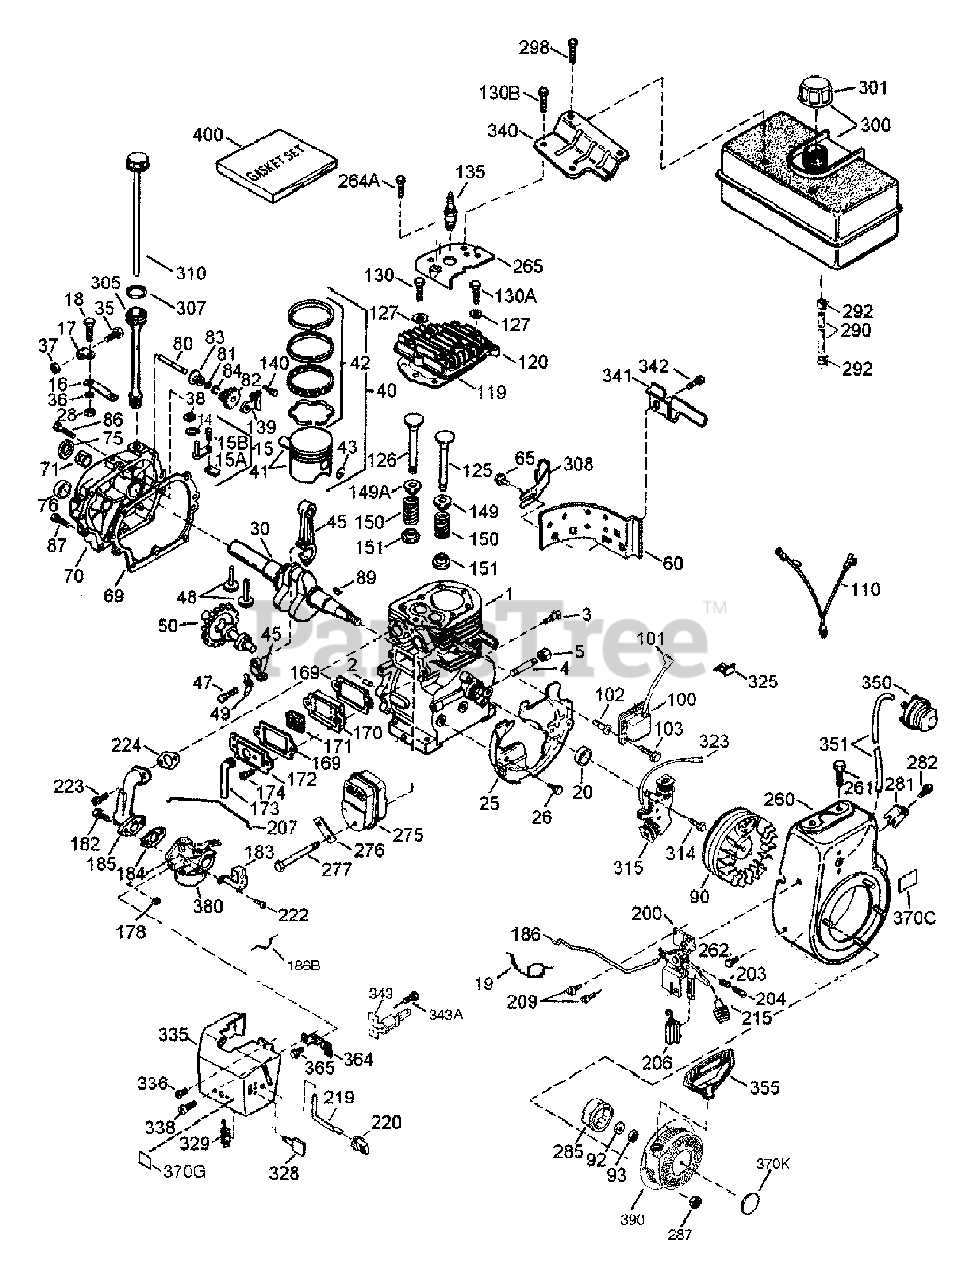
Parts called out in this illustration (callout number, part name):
1	Cylinder Ass'y.
2	Dowel Pin
3	Screw, 1/4-20 x 1/2"
4	Oil Drain Extension
5	Extension Cap
15	Governor Rod
15A	Governor Yoke
15B	Screw, 6-40 x 5/16"
16	Governor Lever
17	Governor Lever Clamp
18	Screw, T-15, 8-32 x 7/16"
19	Speed Control Spring
25	Blower Housing Baffle
26	Screw, 1/4-20 x 19/32"
28	Lock Nut, 8-32
30	Crankshaft
35	Screw, 10-32 x 3/4"
36	Lock Washer
37	Lock Nut, 10-32
38	Retaining Ring
40	Piston, Pin & Ring Set (Std.)
40	Piston, Pin & Ring Set (.010" OS)
41	Piston & Pin Ass'y. (Std.)
41	Piston & Pin Ass'y. (.010" OS)
42	Ring Set (Std.)
42	Ring Set (.010" OS)
43	Piston Pin Retaining Ring
45	Connecting Rod Ass'y.
47	Connecting Rod Bolt
48	Valve Lifter
49	Oil Dipper
50	Camshaft (MCR)
60	Blower Housing Extension
65	Screw, 10-24 x 1/2"
69	Cylinder Cover Gasket
70	Cylinder Cover
71	Crankshaft Bushing
76	Camshaft Seal
80	Governor Shaft
82	Governor Gear Ass'y.
83	Governor Spool
84	Retaining Ring
86	Screw, 1/4-20 x 1-3/16"
87	Screw, 1/4-20 x 1-11/16"
89	Flywheel Key
90	Flywheel (W/Ring Gear)
92	Belleville Washer
93	Flywheel Nut
100	Solid State Ignition
101	Spark Plug Cover
102	Solid State Mounting Stud
103	Screw, T-15, 10-24 x 15/16"
110	Ground Wire
119	Cylinder Head Gasket
120	Cylinder Head
125	Exhaust Valve (Std.)
125	Exhaust Valve (1/32" OS)
126	Intake Valve (Std.)
130	Screw, 5/16-18 x 1-1/2"
130A	Screw, 5/16-18 x 1-25/32"
130B	Screw, 5/16-18 x 39/64"
135	Resistor Spark Plug (RJ19LM)
139	Governor Gear Bracket
140	Screw, 10-24 x 1/2"
149	Valve Spring Cap
149A	Valve Spring Cap
150	Valve Spring
151	Valve Spring Keeper
169	Valve Cover Gasket
170	Breather Body
171	Breather Element
172	Valve Cover
173	Breather Tube
174	Screw, 10-24 x 1/2"
178	Nut & Lock Washer, 1/4-28
182	Screw, 1/4-28 x 1"
183	Choke Bracket
184	Carburetor To Intake Pipe Gasket
185	Intake Pipe
186	Governor Link
186B	Choke Spring
200	Control Bracket
203	Compression Spring
204	Screw, T-10, 5-40 x 7/16"
207	Throttle Link
209	Screw, 10-32 x 1/2"
215	Control Knob
219	Choke Rod
220	Choke Knob
222	Screw, 10-32 x 1/2"
223	Screw, T-30, 5/16-18 x 1-3/32"
224	Intake Pipe Gasket
260	Blower Housing
261	Screw, 5/16-18 x 3/4"
262	Screw, T-40, 5/16-24 x 21/32"
264A	Screw, 1/4-20 x 5/8"
265	Cylinder Head Cover (Black)
276	Locking Plate
277	Screw, 5/16-18 x 4-3/16"
281	Starter Bubble Cover
282	Screw, 8-32 x 3/8"
285	Starter Cup
287	Nut & Lock Washer, 1/4-28
290	Fuel Line
292	Fuel Line Clamp
298	Screw, 1/4-15 x 7/8"
300	Fuel Tank
301	Fuel Cap
305	Oil Fill Tube
308	Fill Tube Clip
314	Screw, 1/4-20 x 3/4"
315	Alternator Coil (3/5 Split)
325	Wire Clip
328	Ignition Key
335	Carburetor Cover (Black)
336	Screw, 10-32 x 1/2"
338	Screw, 10-32 x 3/8"
340	Fuel Tank Bracket (Black)
341	Fuel Tank Bracket
342	Screw, 1/4-20 x 19/32"
343	Key Switch Bracket
343A	Screw, 10-32 x 32/64"
350	Primer Bulb
351	Primer Line (12.00")
355	Starter Handle (Mitten Grip)
364	Carburetor Cover Bracket
365	Screw, 8-32 x 27/64"
370C	Primer Decal
370D	Caution Decal
370G	Instruction Decal
370K	Starter Decal
370R	Warning Decal
380	Carburetor
390	Rewind Starter
400	Gasket Set
